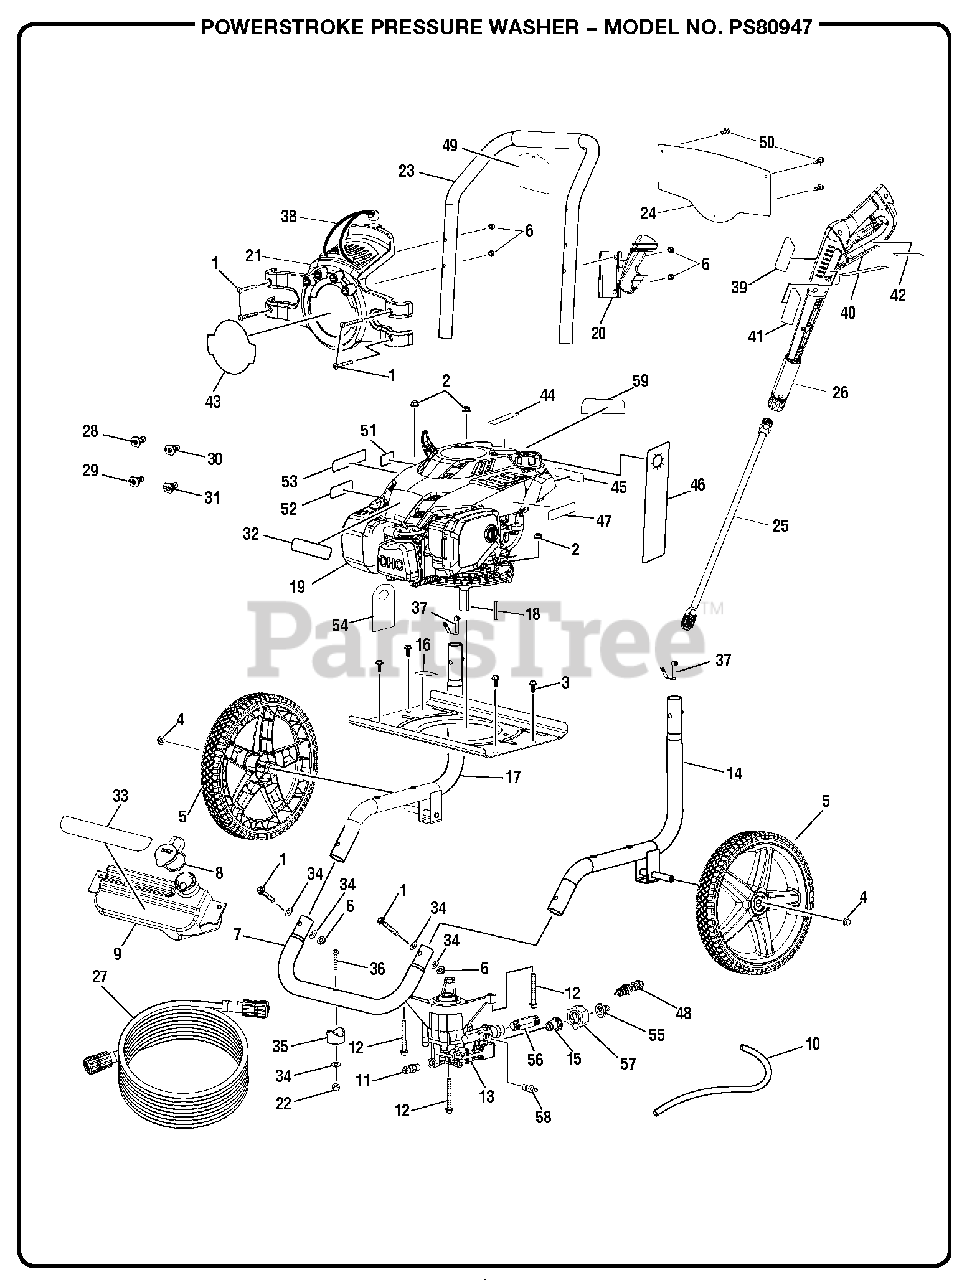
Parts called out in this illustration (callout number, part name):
1	Screw (M6 x 48 mm, T30 Torx Hd. )
2	Flange Nut (M8 x 1.25 in.)
3	Bolt (M6 x 16 mm, Flanged Hex Hd.)
4	Metal Cap
5	Wheel
6	Lock Nut (M6)
7	Front Frame Assembly
8	Soap Tank Cap
9	Soap Tank
10	Chemical Siphon Tube
11	Thermal Release Valve
12	Bolt (M8 x 60 mm, Flange Hd.)
13	Pump
14	Main Frame Assembly (Right)
16	Oil Fill Location Label
17	Main Frame Assembly (Left)
18	Output Shaft Key
20	Wand Holder
21	Hose and Nozzle Assembly
22	Lock Nut (1/4-20)
23	Handle w/Foam
24	Quick Start Panel
25	Spray Wand Assembly
26	Trigger Handle Assembly
28	Soap Nozzle
29	25deg Nozzle
30	40deg Nozzle
31	0deg Nozzle
32	Subaru Label
33	Detergent Tank Label
34	Washer (1/4 in.)
36	Screw (1/4-20 x 1.85 in., T30 Torx Hd.)
37	Spring Clip
38	Bungee Cord Assembly
39	Label (Trigger Handle Logo)
40	Label (Trigger Handle Specifications)
41	Label (Trigger Handle Warning)
42	Label (Trigger Handle Warning, French & Spanish)
43	Performance Label
44	E85 Label
45	Do Not Mix Label
46	Warning Hangtag
47	Engine Control Label
48	Unloader Assembly
49	Nozzle Hangtag
50	Screw (#6-20 x 3/8 in., T10 Torx Pan Hd.)
51	Lubricant Label
52	Hot Surface Label
53	Combustion Label
54	Oil Dipstick Hangtag
55	Filter Screen
56	Outlet Tube
58	Soap Injector Kit
59	Danger Label
